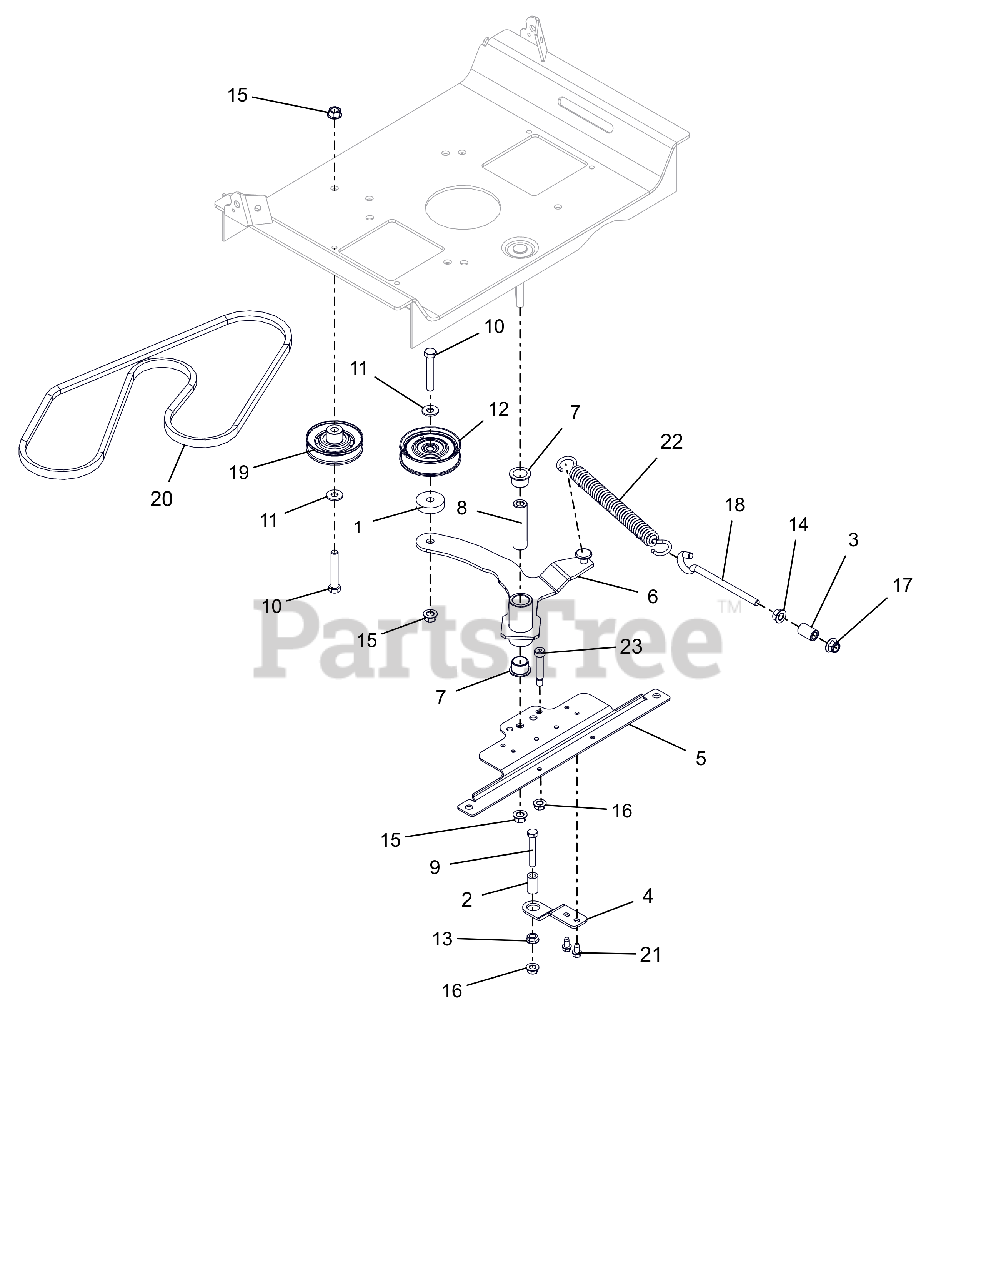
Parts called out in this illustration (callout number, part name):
1	SPACER, .39 X 1.50 X .380
2	SPACER, RUBBER 5/16 IDX1.0 LG
3	SPACER, .375X.625X.970 (PM)
4	BRKT, CLUTCH STOP
5	BRKT, DRIVE IDLER MOUNTING
6	WLDMT,GRD DRIVE IDLER ARM-LGR
7	BSHG-FLG 0.75X0.875X.625X1.125
8	BUSHING, SLEEVE .38X.750X2.78
9	@BLT-HEX .31-18X2.00 GR5 YWZC
10	@BLT-HEX .38-16X2.25 GR5 YWZC
11	@WSHR-FL-STL.38X.875X.083 YWZC
12	IDLER, FLAT - 3.05" X .75"
13	@NUT-SPNLK-FLG .312-18 YWZC
14	@NUT-SPNLK-FLG .375-16 YWZC
15	@NUT-LK-TOP-FLG .38-16 YWZC
16	@NUT-LK-TOP-FLG .31-18 YWZC
17	@NUT-LK-NYL-FLG .38-16 YWZC
18	BOLT,.38-16 X 4.25-.62 DIA EYE
19	IDLER, V-3.000 OD
20	V-BELT, A-RAW EDGE
21	SCR-TAP .25-20X.50 HWH TR YWZ
22	SPRING, EXTENSION
23	BLT-SHLDR .38X1.5X.31-18 SLT Y
